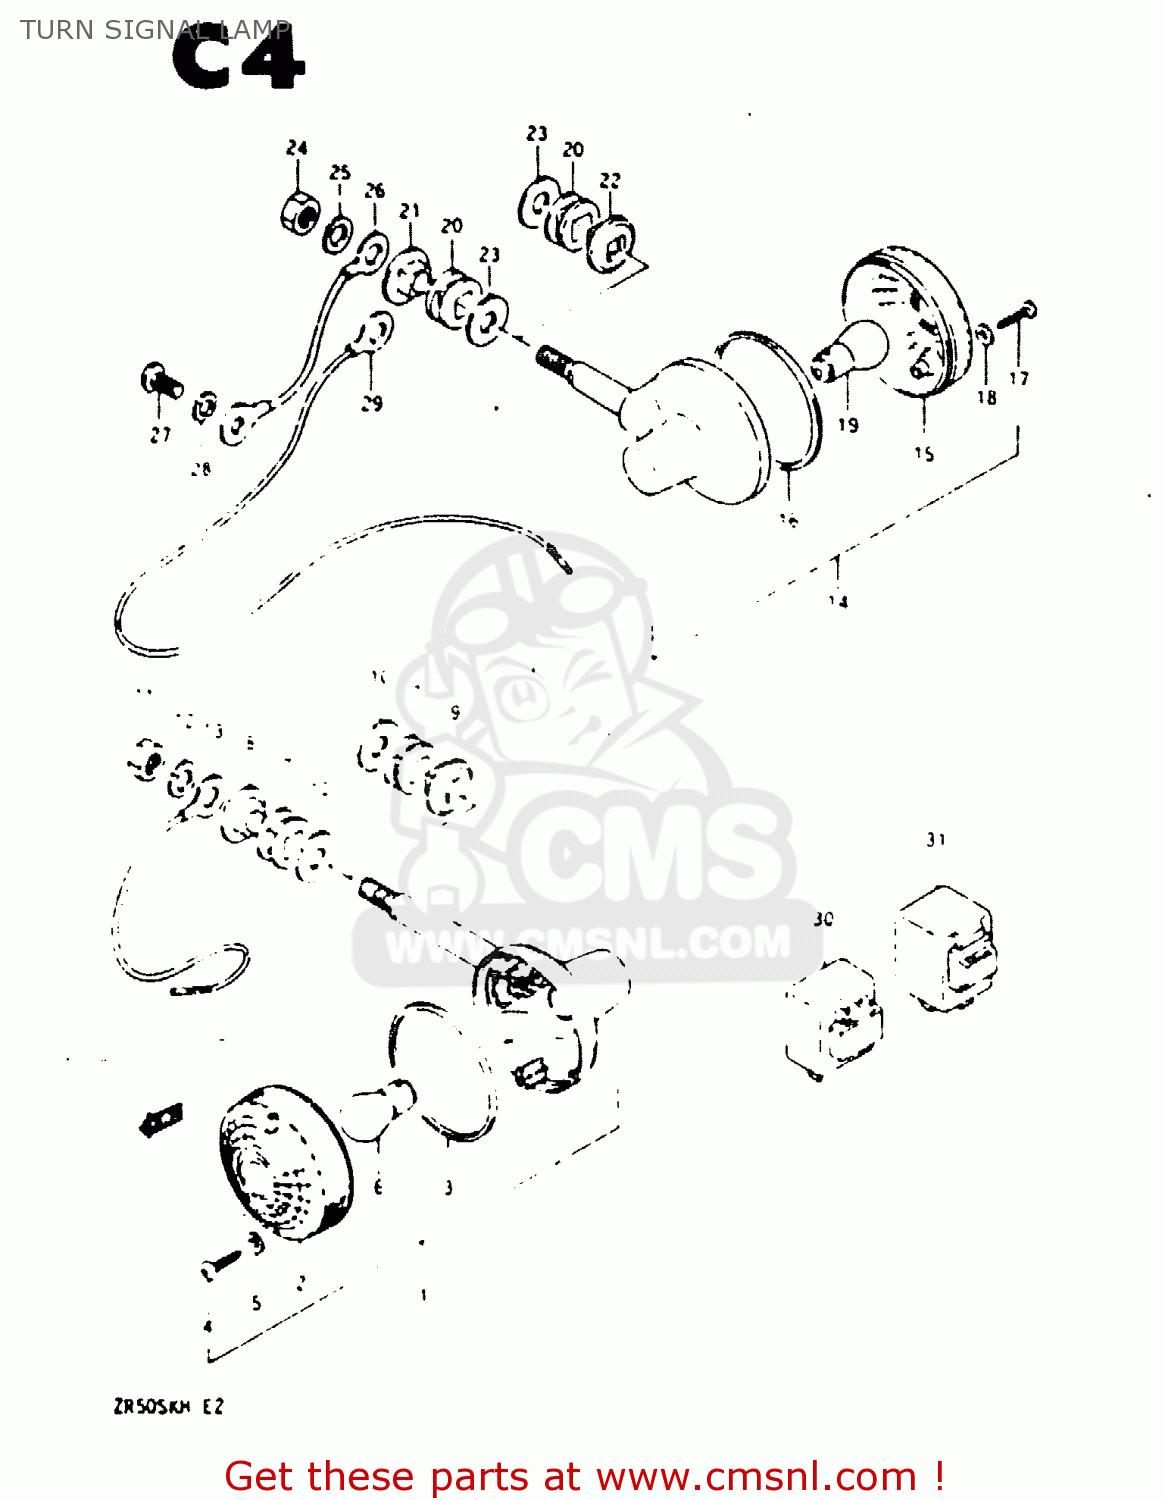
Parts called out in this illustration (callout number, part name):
1	LAMP, FRONT TURN SIGNAL
2	LENS
3	GASKET (NAS)
4	SCREW
5	GASKET (NAS)
6	BULB (6V,18W)
7	CUSHION
8	SPACER
9	SPACER
10	WASHER (10.5X30X2.3)
11	NUT
12	LOCK WASHER
13	LEAD WIRE,EARTH
14	LAMP ASSY, REAR TURN SIGNAL
15	LENS
16	GASKET (NAS)
17	SCREW
18	GASKET (NAS)
19	BULB (6V,18W)
20	CUSHION
21	SPACER
22	SPACER
23	WASHER (10.5*30*2.3)
24	NUT
25	WASHER,LOCK,10
26	LEAD WIRE
27	SCREW
28	WASHER,LOCK
29	LEAD WIRE, EARTH
30	RELAY,TURN SIGNAL
32	RELAY ASSY, TURN SIGNAL
